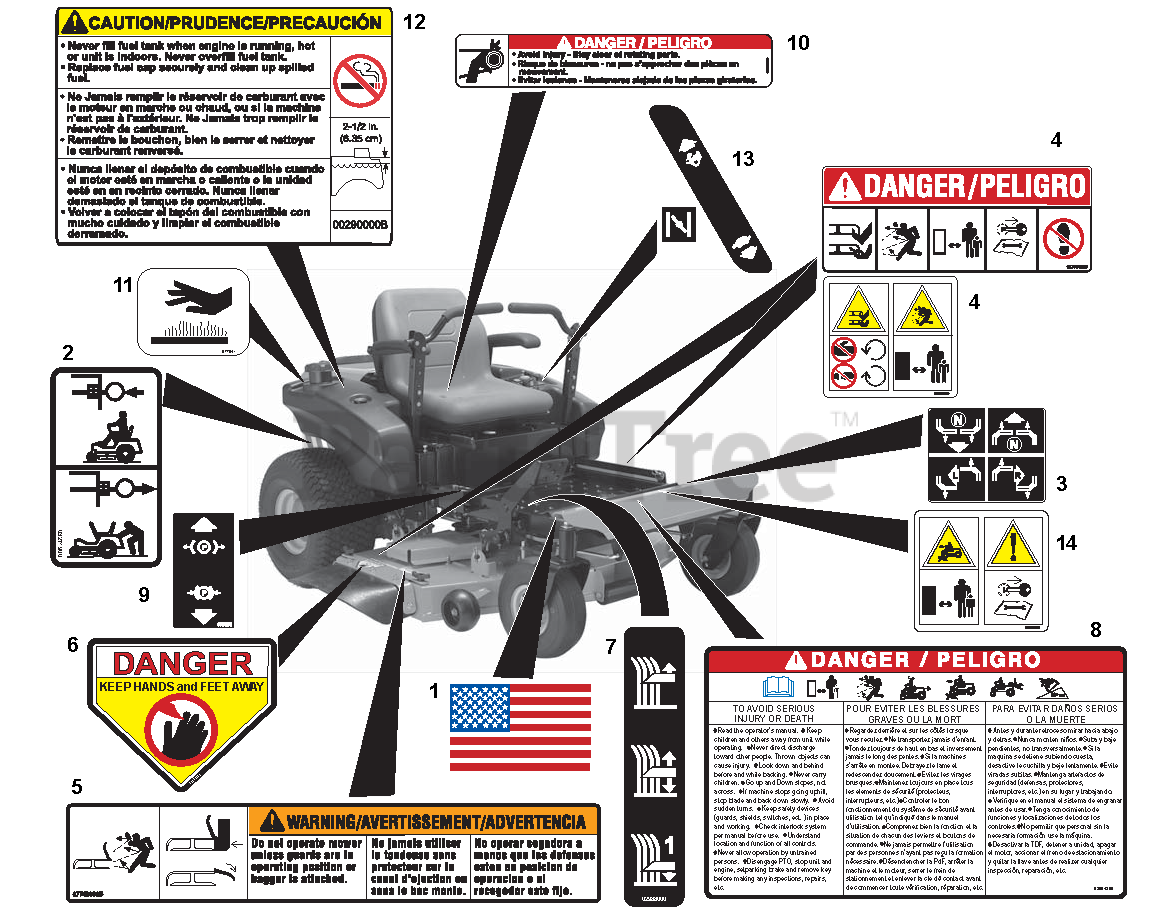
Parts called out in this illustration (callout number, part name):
1	DECAL, AMERICAN FLAG
2	DECAL, TRANSMISSION DISCONNECT
3	DECAL, INSTRUCTIONAL-STEERING
4	DECAL, MOWER PAN DANGER
5	DECAL, WARNING
6	DECAL, DANGER
7	DECAL, CUT HEIGHT
8	DECAL, DANGER BILINGUAL
9	DECAL, PARKING BRAKE LEVER
10	DECAL- DANGER
11	DECAL, HOT SURFACE
12	DECAL,FUEL WARNING
13	DECAL, SPEED CONTROL
14	DECAL, CE CAUTION
